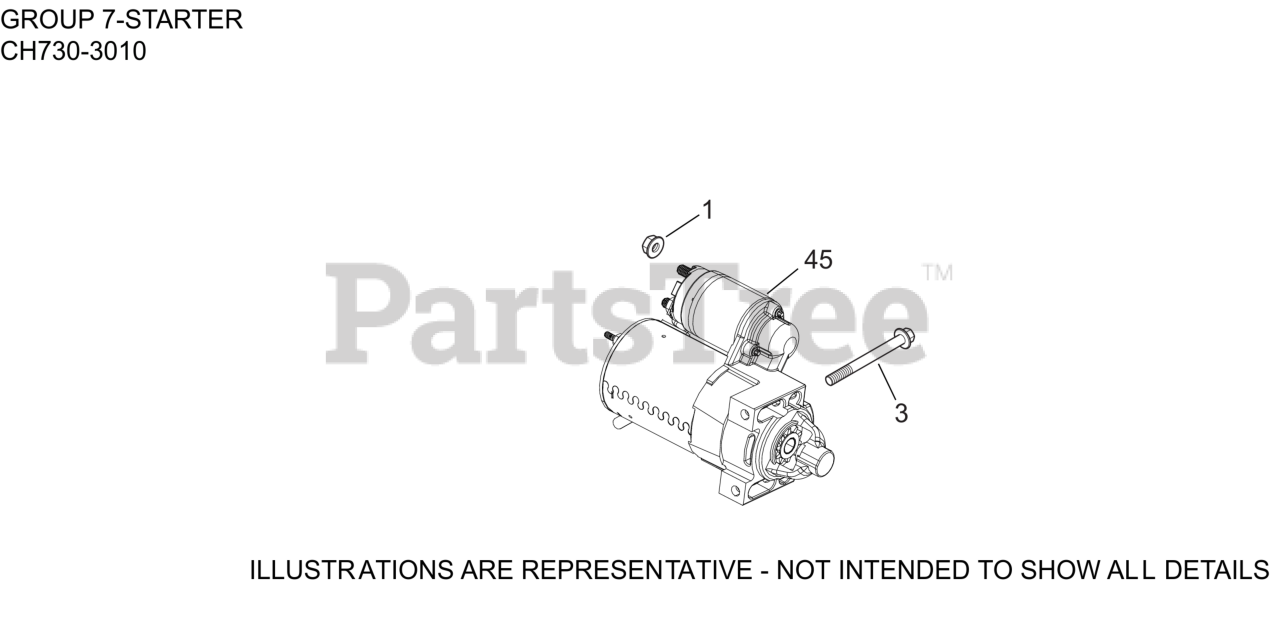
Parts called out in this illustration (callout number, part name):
1	NUT, FLG M8X1.25
3	SCREW, FLG M8X1.25X80
45	STARTER, SOLENOID SHIFT (25 098 09-S)
